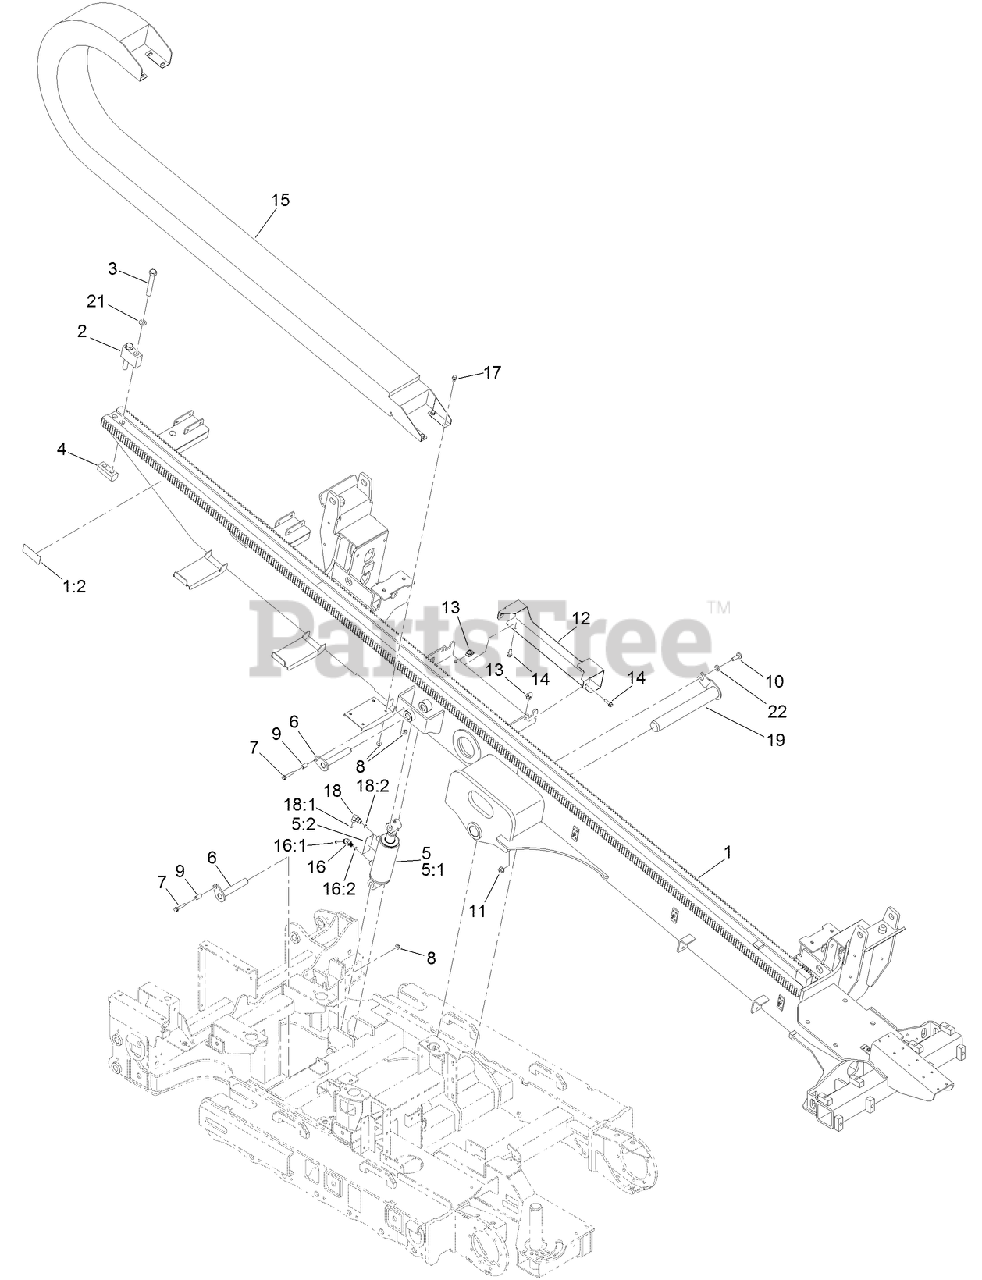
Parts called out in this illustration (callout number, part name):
1	THRUST FRAME ASM
1:2	DECAL-DANGER, CRUSHING
2	STOP-CARRIAGE
3	SCREW-HH
4	BLOCK-TAPPED
5	LIFT CYLINDER ASM
5:1	CYLINDER-HYDRAULIC
5:2	DECAL-CAUTION, CYLINDER LOCK
6	PIN-PIVOT
7	SCREW-HHF
8	NUT-HF, NI
9	SPACER
10	SCREW-HSBH
11	NUT-HHF, WHIZ
12	COVER-MANIFOLD
14	SCREW-HHF
15	CARRIER-HOSE
16	FITTING-ELBOW, 45 DEG
16:1	O-RING
16:2	O-RING
18	FITTING-ELBOW, 90 DEG
18:1	O-RING
18:2	O-RING
19	PIN-FRAME, THRUST
21	WASHER
22	WASHER
